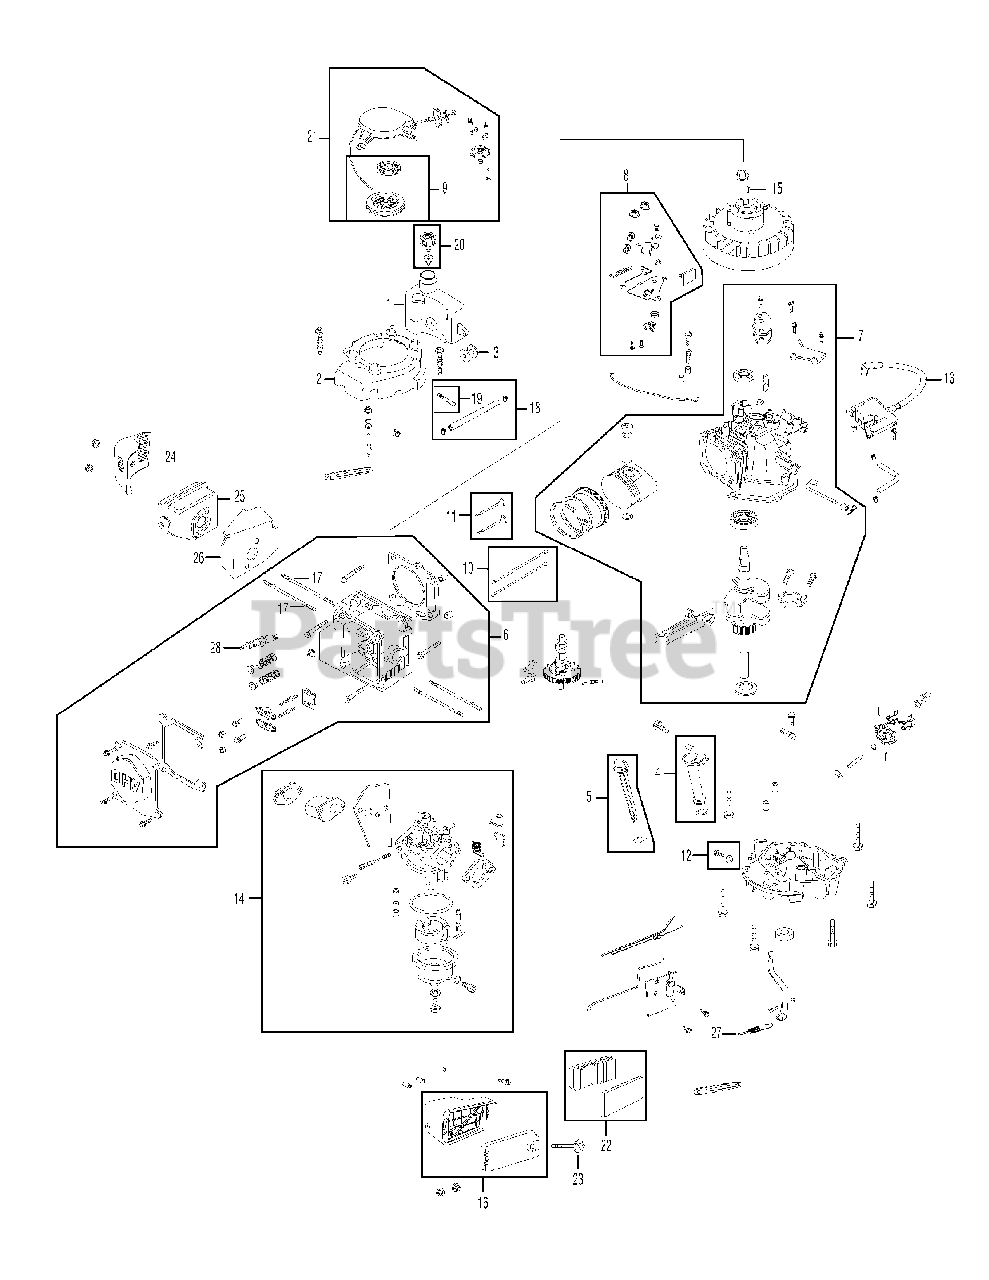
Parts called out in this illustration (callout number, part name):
1	Fuel Tank
2	Flywheel Shroud
3	Rubber Fuel Tank Mounting Washer
4	Oil Filler Tube Assembly
5	Dipstick Assembly
6	Cylinder Head Complete
7	Short Block Assembly
8	Stop Switch and Brake Assembly
9	Recoil Spring and Pulley Assembly
10	Push Rod Kit
12	Oil Drain Plug and Washer Assembly
13	Ignition Coil
14	Carburetor Assembly
15	Flywheel Key
16	Air Cleaner Housing Assembly Complete
17	Muffler Stud Assembly
18	Fuel Line Kit - Inc. hoses, clamps & filter
19	Fuel Filter
20	Fuel Cap Assembly
21	Recoil Starter Assembly
22	Air Cleaner Kit
23	Air Cleaner Thumb Screw
24	Muffler Guard
26	Muffler Gasket /Heat Shield
27	Governor Return Spring
28	Spark Plug
